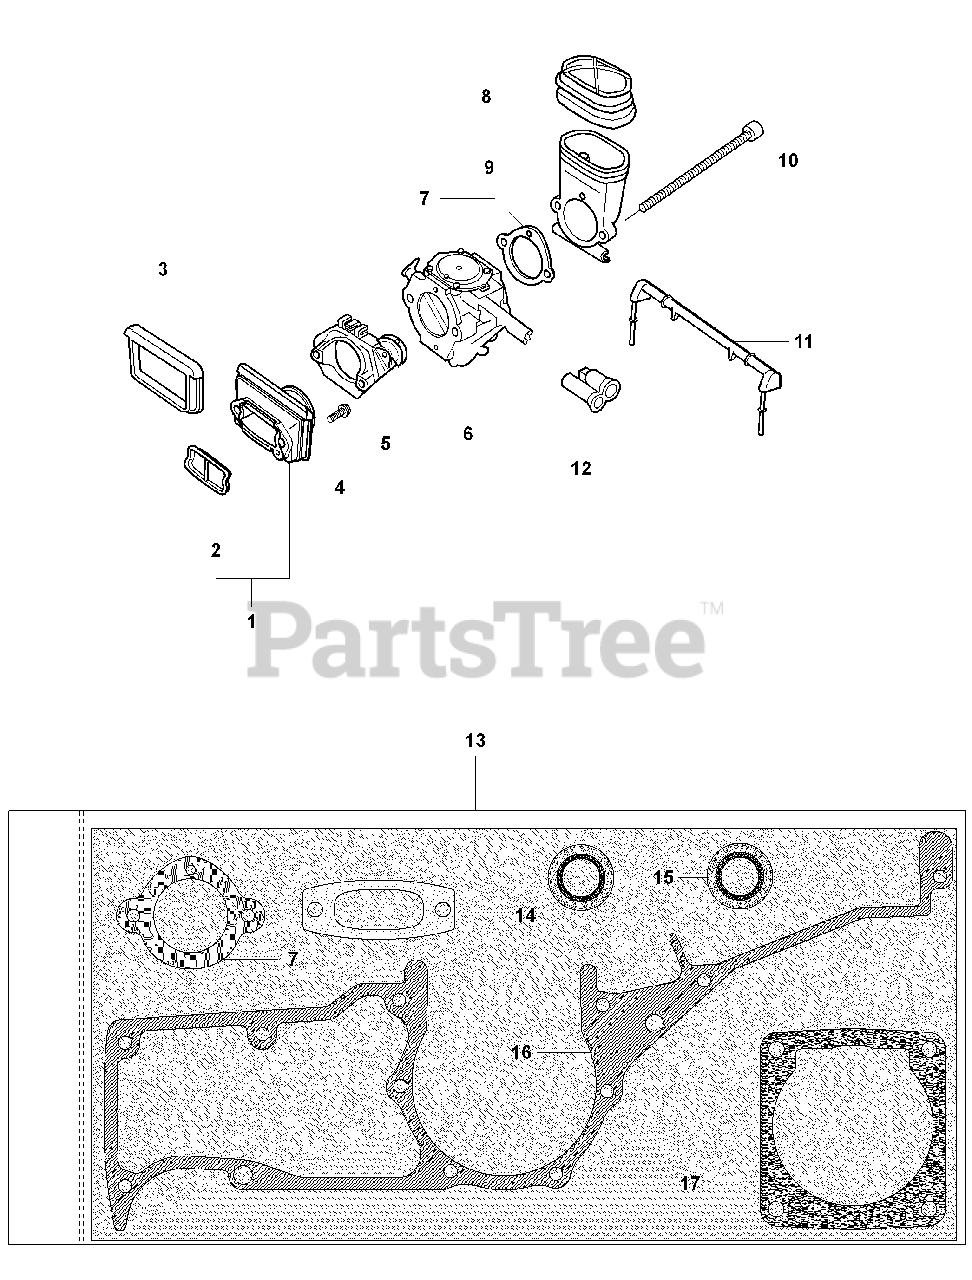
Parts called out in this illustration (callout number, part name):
1	INLET PIPE
6	CARBURETTOR
7	GASKET
9	INLET BEND
12	CHISEL GUIDE
13	GASKET KIT
14	GASKET MUFFLER
15	SEALING RING
16	CRANKCASE GASKET
